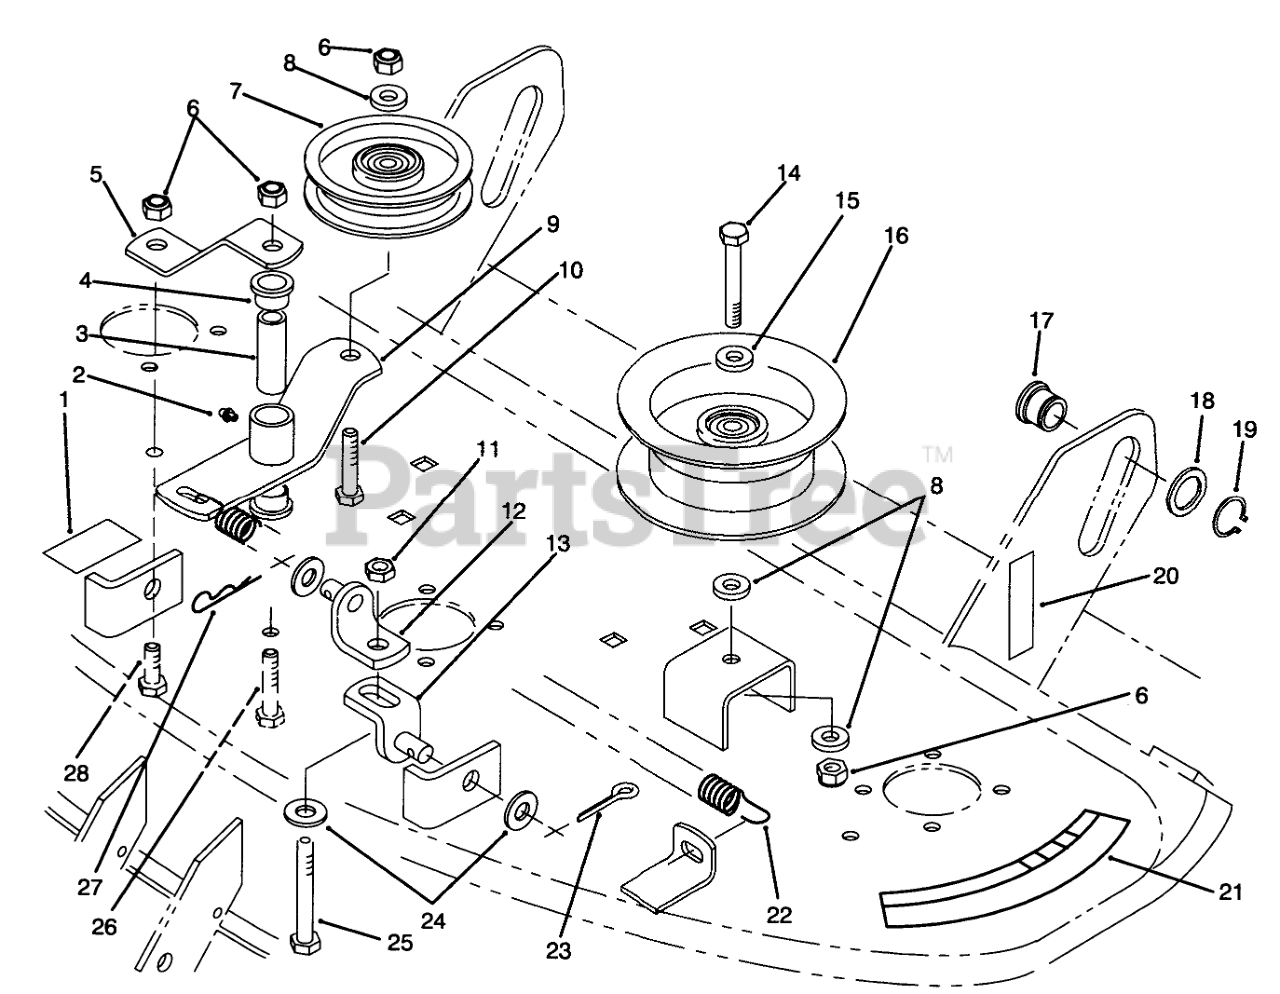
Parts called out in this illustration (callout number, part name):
1	DECAL-BELT INSTALL
2	FITTING-GREASE
3	SPACER
4	BUSHING
5	Strap-Brace
6	NUT-LOCK, NI
7	Pulley-Idler
8	WASHER-FLAT
9	Arm-Idler
10	SCREW-HH
11	NUT-JAM
12	BRACKET-LIFT, UPPER
13	BRACKET-LIFT, LOWER
14	SCREW-HH
15	WASHER
16	Pulley-Idler
17	ROLLER-LIFT
18	Washer
19	RING-RETAINING
20	Decal-Attach-A-Matic
21	DECAL - DANGER
22	SPRING - EXTENSION
23	PIN-COTTER
24	WASHER-FLAT
25	SCREW-HH
26	SCREW-HH
27	Hairpin
28	SCREW-HH
